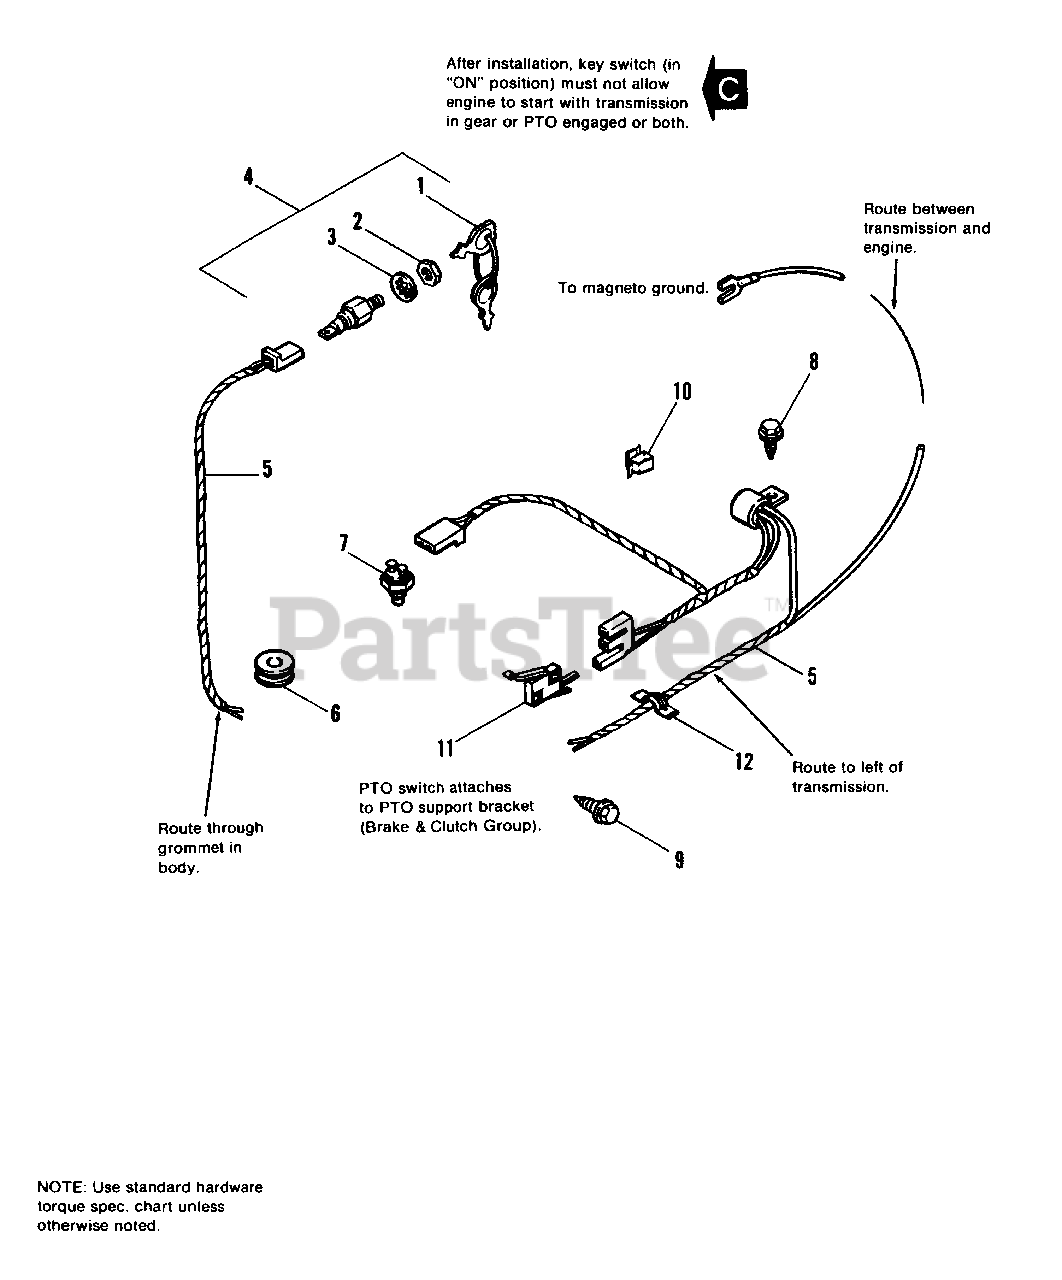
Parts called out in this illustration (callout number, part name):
2	NUT
3	LOCKWASHER, Internal Tooth, 5/8
4	SWITCH, Key
5	HARNESS ASSY.
7	SWITCH, Transmission Interlock
8	SCREW, Hex, Taptite, 1/4-20 x 3/8
9	SCREW, Hex, Taptite, #5-40 x 3/4
10	CLIP, Tinnerman
11	SWITCH, P.T.O. Interlock
12	CLIP, Wire
